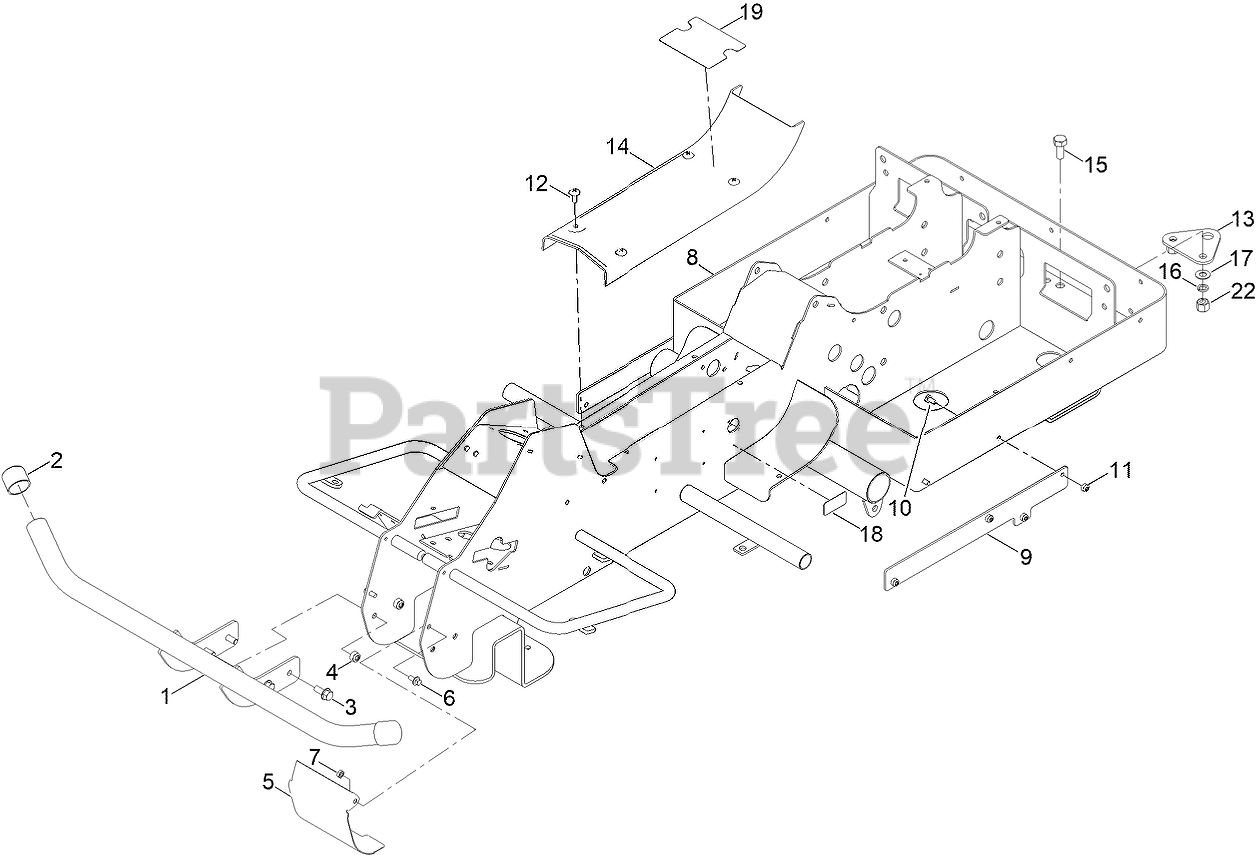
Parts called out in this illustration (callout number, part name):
1	BUMPER BAR, ASM
2	CAP, BUMPER BAR
3	SCREW-HHF
4	NUT-HEX, NI
5	FRONT PLATE, MAIN CHASSIS
6	BOLT, FLANGE
8	CHASSIS ASM
9	MOUNTS, SIDE PANNEL
10	SCREW-HH
11	NUT-NYLOC
12	CAP BOLT
13	TOW HITCH
14	TOP COVER, CHASSIS
15	SCREW-HH
16	WASHER-LOCK
17	WASHER-PLAIN
18	DECAL - CHARGING PORT
19	DECAL - DANGER
